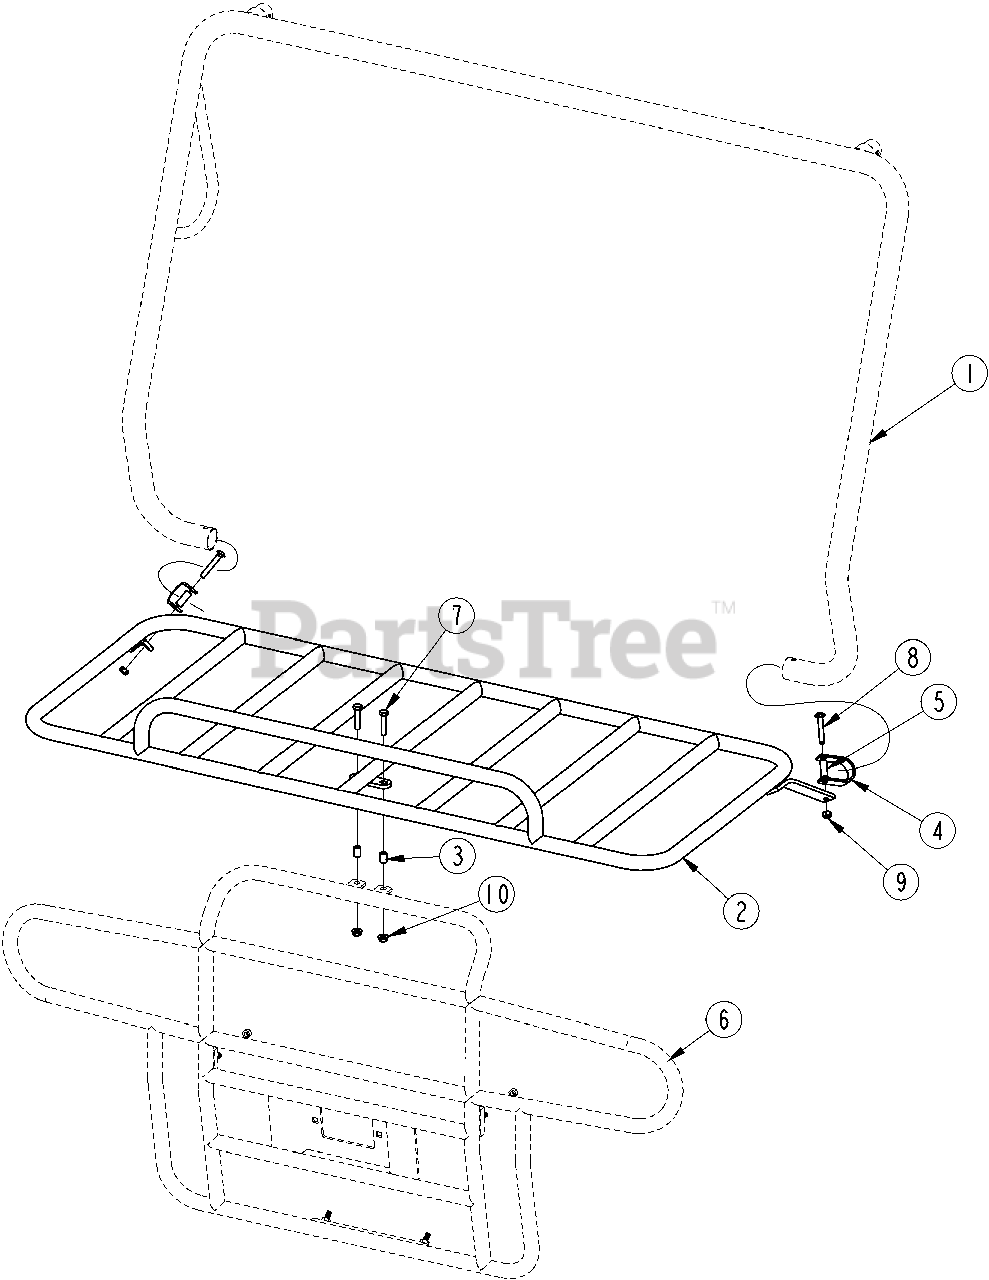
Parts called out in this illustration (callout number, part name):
2	ST Front Cargo Rack
3	5/8 U-Clamp Spacer
4	1-1/2" U-Clamp
5	1-1/8" U-Clamp Spacer
7	5/16-18 x 1-1/2 Hex Head Cap Screw
8	5/16-18 x 2 Round Head Square Neck Bolt
10	5/16-18 Nylock Hex Nut
